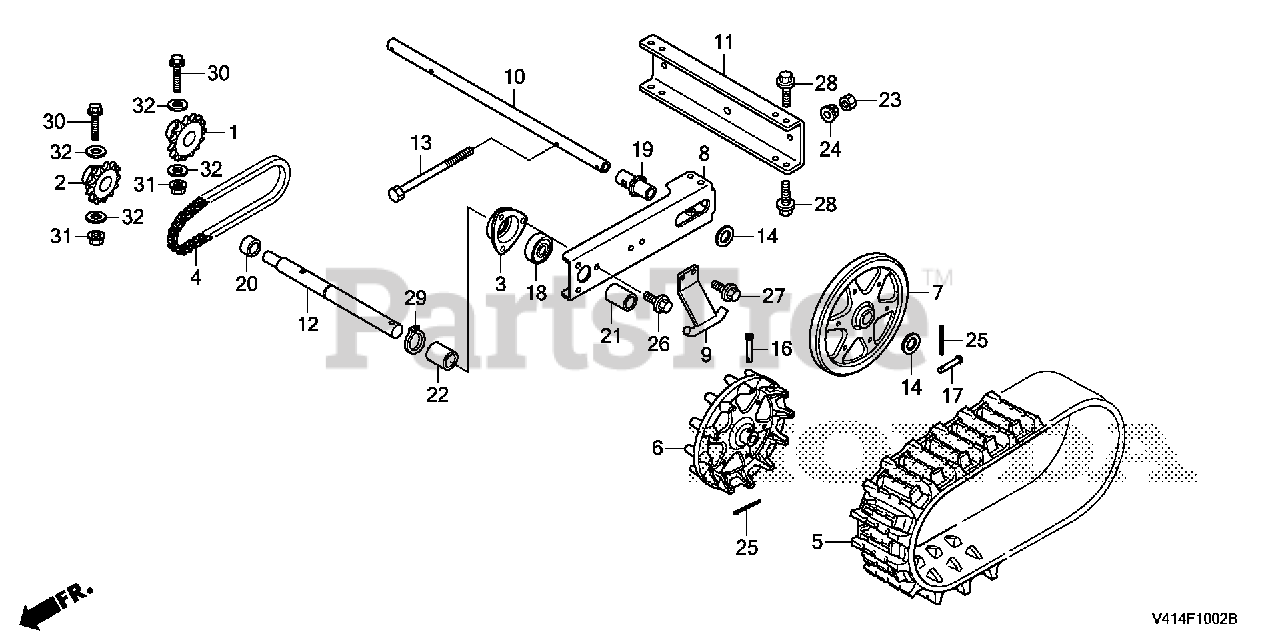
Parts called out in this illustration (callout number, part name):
1	SPROCKET, DRIVE (15T)
2	SPROCKET, DRIVEN (13T)
3	HOLDER, BEARING
4	CHAIN, DRIVE
5	CRAWLER (58.5X21)
6	SPROCKET, CRAWLER *NH314* (CONDUCT GRAY)
7	ROLLER, CRAWLER *NH314* (CONDUCT GRAY)
8	PLATE, CRAWLER
9	GUIDE, CRAWLER
10	PIPE, CRAWLER
11	BAR, CRAWLER PLATE
12	SHAFT, FR. AXLE
13	BOLT, HEX. (8X110)
14	WASHER, PLAIN (22.5MM)
15	PIN (6X33) (NA USE ALT:90102-V45-A00)
16	PIN (6X34)
17	PIN, SPECIAL (6X29)
18	BEARING, RADIAL BALL (6203-19.05)
19	COLLAR, CRAWLER PIPE
20	COLLAR, CRAWLER SPROCKET
21	COLLAR B, CRAWLER SPROCKET
22	COLLAR C, CRAWLER SPROCKET
23	NUT, HEX. (8MM)
24	NUT-WASHER (8MM)
25	PIN, SPLIT (3.0X18)
26	BOLT, FLANGE (8X16)
27	BOLT, FLANGE (8X16)
28	BOLT, FLANGE (8X20)
29	CIRCLIP (OUTER) (19)
30	BOLT, FLANGE (6X50)
31	NUT, NYLON RING (6MM)
31	NUT, SELF-LOCK (6MM)
32	WASHER, PLAIN (6MM)
